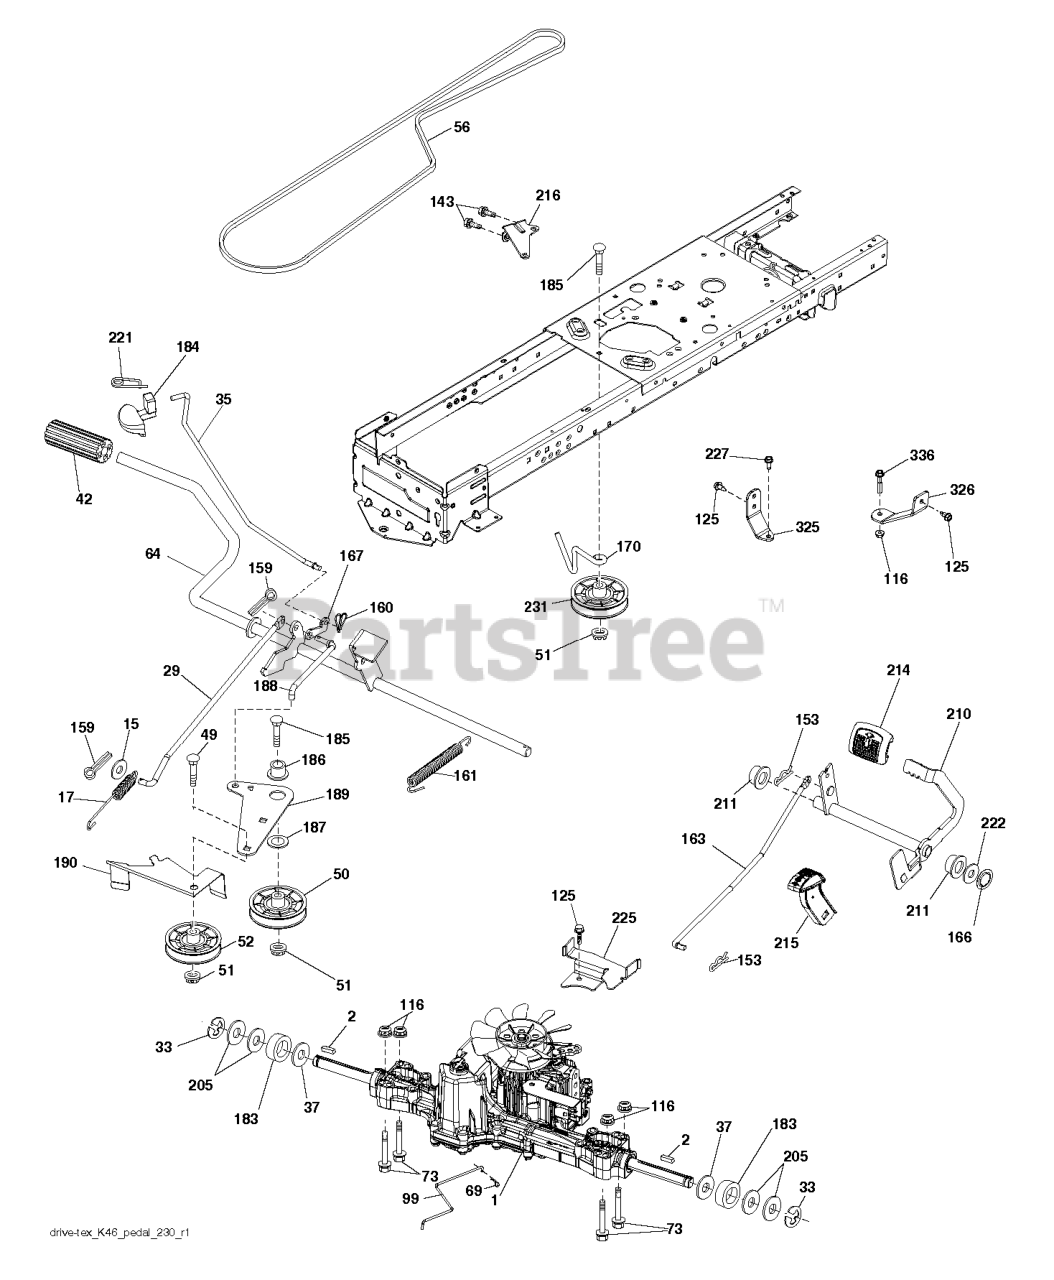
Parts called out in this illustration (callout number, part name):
2	SQUARE KEY
15	WASHER
17	SPRING.BRAKE.K46.GREEN
29	ROD.BRAKE.K46
37	WASHER.HARDENED
42	PEDAL COVER
50	IDLER.FLAT.910.OFFSET
51	NUT LOCK FLG 3/8-16 UNC
52	IDLER.V-GROOVE.910.OFFSET
64	SHAFT.ASM.PEDAL.BRK.CNTR
69	HAIRPIN.SOFT.ZINC.059X1.125
99	ARM.PIVOTING.TCRD.GEN2.5.BAGGE
125	SCREW
153	RETAINER M
160	GSPW Retainers
161	SPRING, RETURN LT
166	NUT.PUSH.625
167	LATCH.BRAKE.SPRING
170	KEEPER.CENTER SPAN.1.688
183	SPACER AXLE
184	HANDLE.PARKNG BRK.PRED.LT.428
186	SPACER.RETAINER
188	LINK.CLUTCH.GROUND DRIVE.LONG
189	BELLCRANK.GROUND.DRIVE.TEX.
190	KEEPER.BELLCRANK.DRIVE
210	ROCKER.ASM.PEDAL.CONTR
211	BEARING.NYLON
214	PEDAL.FORWARD.PAD.TEX
215	PEDAL.COVER.REVERSE.CRD.X428BK
216	BRACKET.PULLEY.IDLER.W/TEX
221	RETAINER.SPRING.CLIP.H
222	WASHER 21/32 X 1-1/4 X 10 GA.
225	KEEPER.BELT.TRANSAXLE.K46
231	IDLER.V-GROOVE.1.688.OFFSET
325	TORQUE.STRAP.K46.LT.LH
326	BRCKT.PNT.TRQ.STP.46.18TIRE.RH
